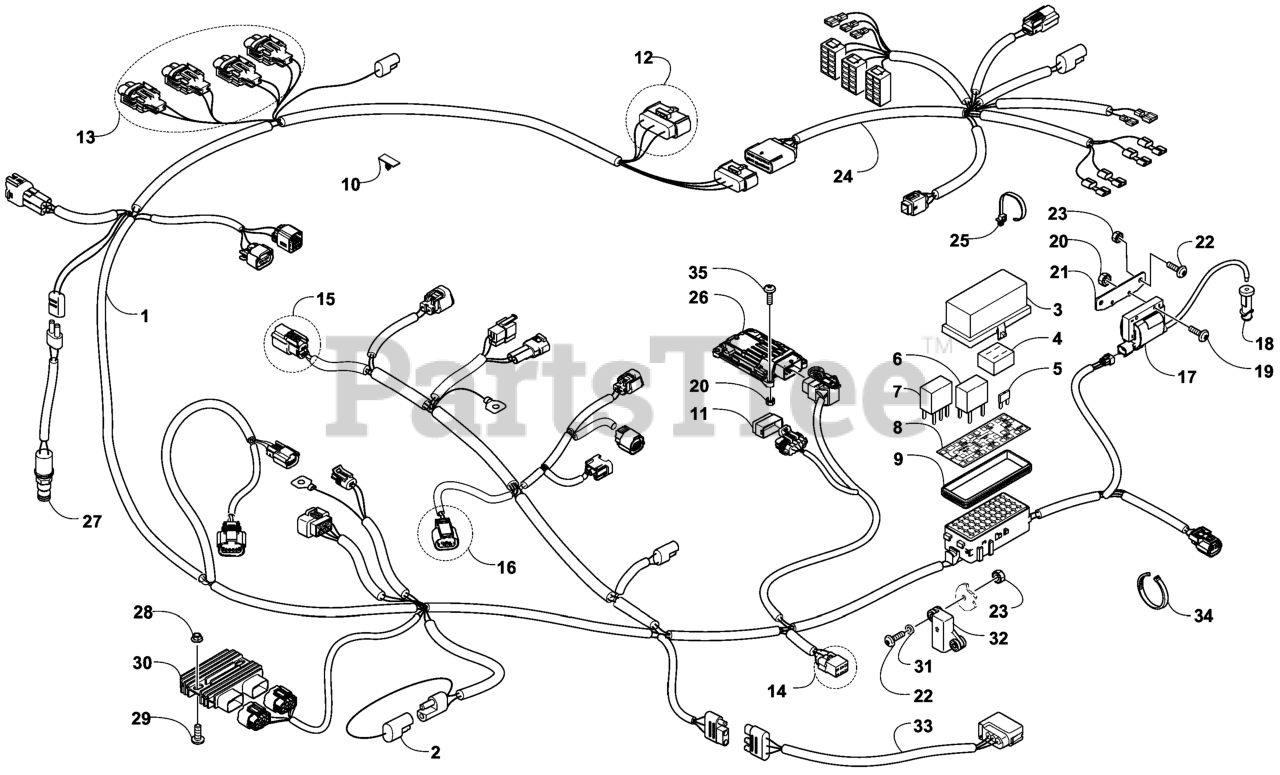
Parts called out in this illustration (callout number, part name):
1	HARNESS-DIA, MAIN
2	TETHER-REAR ACCESSORY CON
4	HOLDER-SPARE FUSE
5	FUSE-MINI, 10A
5	FUSE-MINI, 15A
5	FUSE-MINI, 30A
6	RELAY-SPST
7	RELAY-SPDT
8	DECAL-PDM
9	SEAL-PDM
10	RETAINER-CLIP, HARNESS
11	COVER ASM
12	KIT-CAN GAUGE CONNECTOR
13	KIT-HL CONNECTOR REPAIR (
14	KIT-TILT SENSOR CONNECTOR
15	KIT-REPAIR, ISC
16	KIT-REPAIR, 3P MAP CONNEC
17	COIL/CAP, IGNITION ASM
18	CAP-SPARK PLUG
19	SCREW-TSPRH
20	NUT-HH, SEMS
21	BRACKET-COIL
22	SCREW-TSPNH
24	HARNESS-CONSOLE
25	TIE-CABLE
26	ECM-PROGRAMMED
27	SWITCH-BRAKE, FOOT
28	NUT-HHF
29	SCREW-TSPRH
30	REGULATOR-VOLTAGE
31	WASHER-FLAT
32	SENSOR-INCLINATION
33	HARNESS-ADAPTER, TAIL LIG
34	TIE-CABLE
35	SCREW-TSPRH
